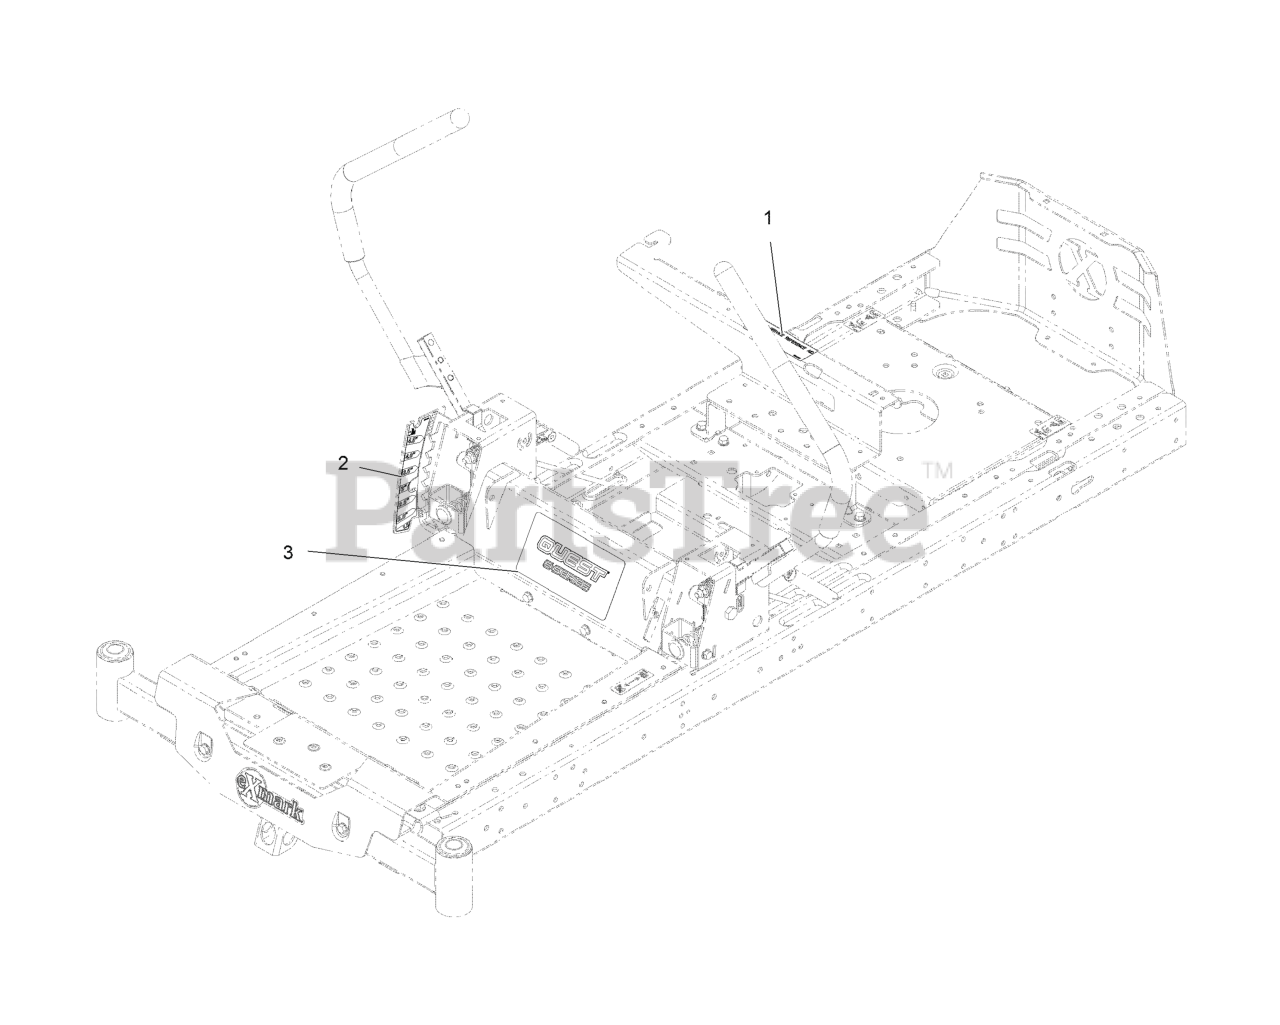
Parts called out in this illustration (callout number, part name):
1	DECAL-SERVICE, CE
2	DECAL-HOC
3	DECAL, QUEST E SERIES
